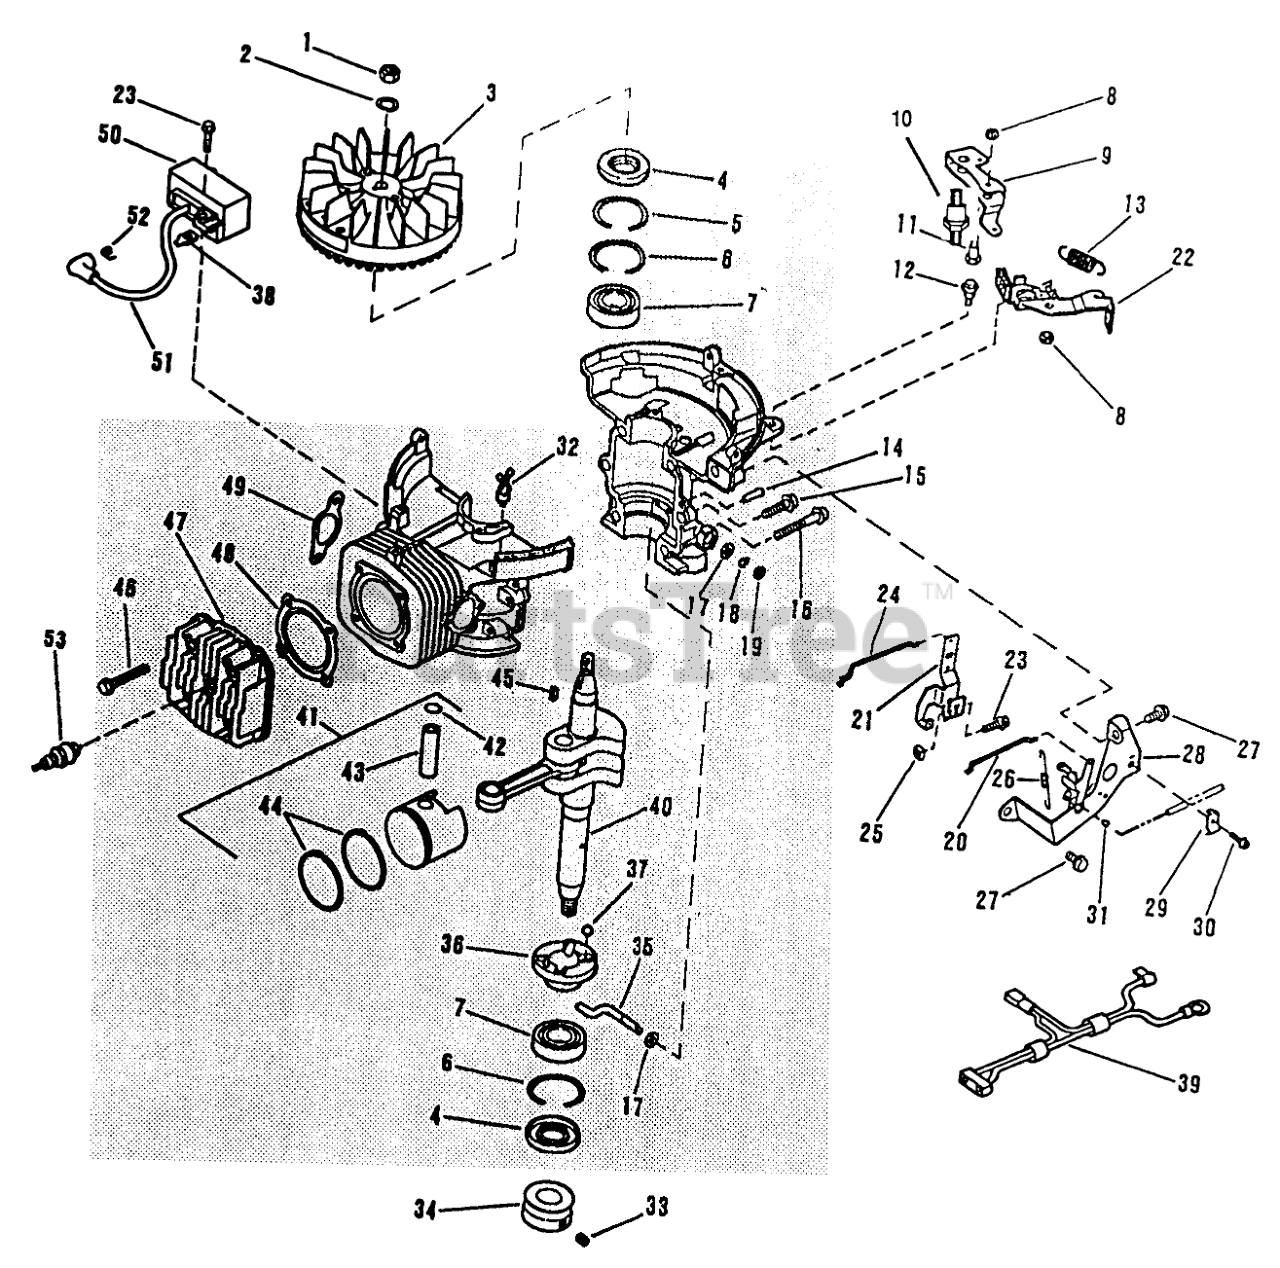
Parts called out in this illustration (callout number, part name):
1	NUT
2	WASHER-LOCK
3	F/WHEEL ALUM SM
4	SEAL - OIL SM
5	RING-RETAINER SM
6	RING RET. SM
7	BEARING-BALL SM
8	LOCKNUT E
8	NUT - HEX JAM
9	ACT.BRAKE LVR. SM
10	STUD-SHOULDER SM
11	BOLT-SHOULDER SM
12	BOLT-SHOULDER SM
13	SPRING-BRAKE
14	PIN, TAPER SM
15	SCREW-H.W.HD. F
16	SCREW-HEX W.H. SM
17	WASHER-FLAT SM
18	RING-RETAINING
19	SEAL - OIL SM
20	ROD - CHOKE SM
21	GOV CTL LEVER SM
22	BRAKE & SWITCH S
23	SCREW
24	ROD-THROTTLE SM
25	NUT SM
26	SPRING-GOV. SM
27	SCREW HEX WASH SM
28	GOVNR BRKT SM
29	CLAMP SM
30	SCREW-CLAMP SM
31	Retainer-Throttle Wire
32	WIRE TIE SM
33	SCREW-SET
34	PULLEY-ENGINE
35	Governor Arm
36	Governor Ramp
37	BALL-GOVERNOR SM
38	TERMINAL M
39	WIRE HARNESS ASSY
40	C/SHAFT&C.ROD SM
41	PISTON&RING AY. S
42	RING-RETAINER SM
43	WRIST PIN SM
44	RING SET S
45	KEY
46	SCREW
47	CYLINDER HEAD SM
48	GASKET-HEAD SM
49	GASKET - EXH SM
50	CD Ignition
51	HI-TENS.LEAD SM
53	Spark Plug
